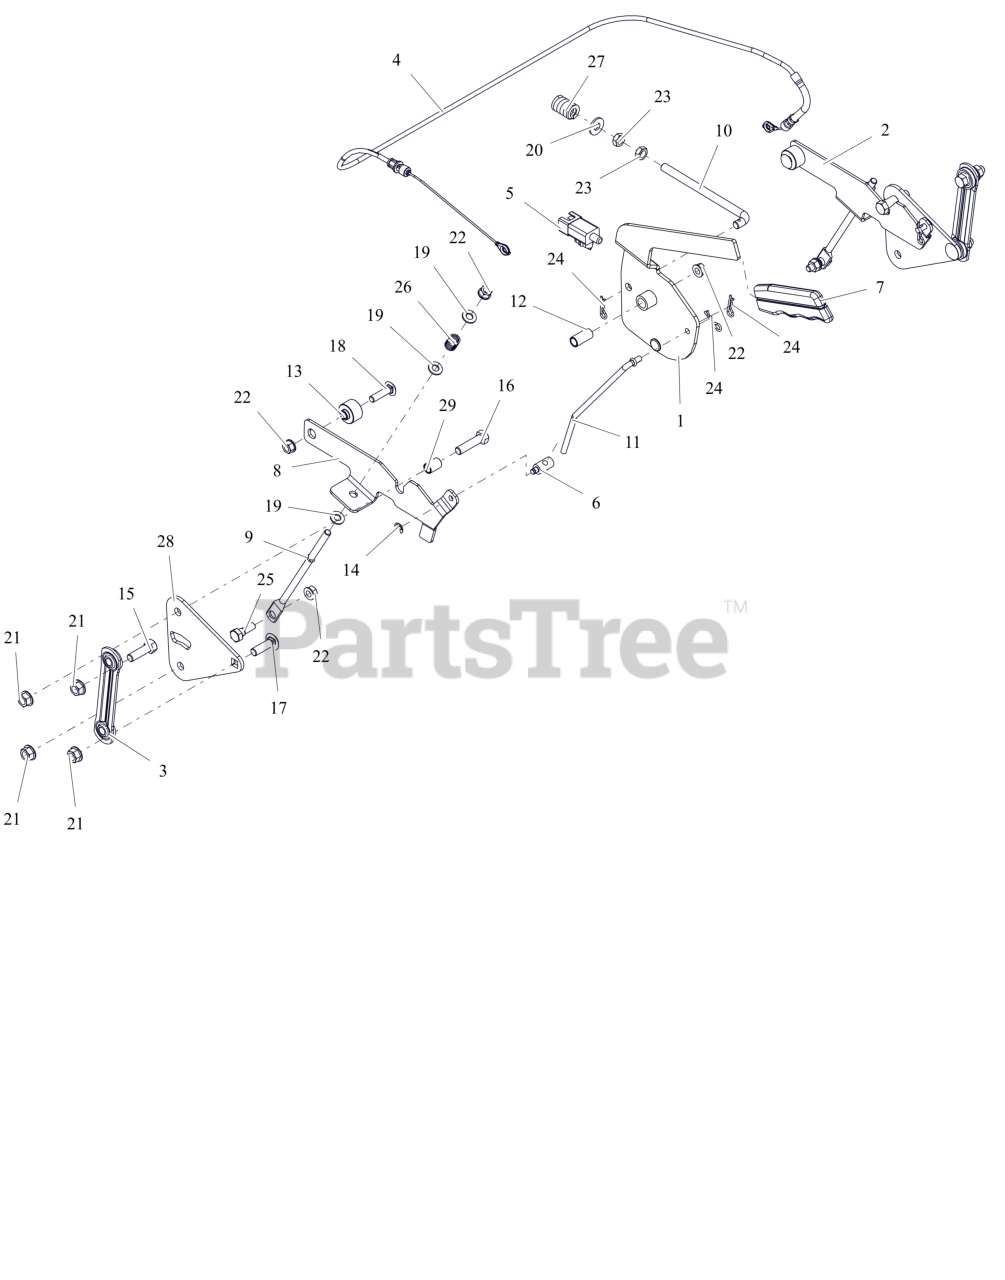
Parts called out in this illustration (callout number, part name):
1	LEVER, PARKING BRAKE
2	ARM, BRAKE - LH (W/PIN)
3	LINK, STAMPED STEERING
4	CABLE, BRAKE - PARKING
5	SWITCH, SNAP IN - N.O./N.O.
6	TRUNION, 1/4-20
7	GRIP, PARKING BRAKE (GREY)
8	ARM, BRAKE - RH
9	ROD, LINK - TRANSMISSION BRAKE
10	ROD, OVER CENTER
11	ROD, BRAKE LINK
12	BSHG-SLV .385X.500X1.045
13	SPCR, FLANGE
14	RG-RTNG-EXT .250X.025
15	BLT, HEX .38-16X1.25 G5 ZCC
16	BLT, HEX .38-16X1.50 G5 ZCC
17	BLT,RHSSN .38-16X1.25 G5 ZCC
18	BLT, RHSSN.31-18X1.25 G5 ZCC
19	WSHR,FLT .344X.688X.065 ZCC
20	WSHR,FLT .375X.875X.083 ZCC
21	NUT-LK-TOP-FLG .38-16 ZC120
22	NUT-LK-TOP-FLG .312-18 GF ZCC
23	NUT-JAM .375-16 G2 ZCC
24	PIN, HAIR #213 .08X1.19 ZCC
25	BOLT,SHLDR .38X.25 -.31-18X.75
26	SPRING, COMPRESSION
27	SG-COMP .187X.56X1.62
28	PLATE, TRANSAXLE (BLACK)
29	SPCR SLEEVED .385X.500X.718
